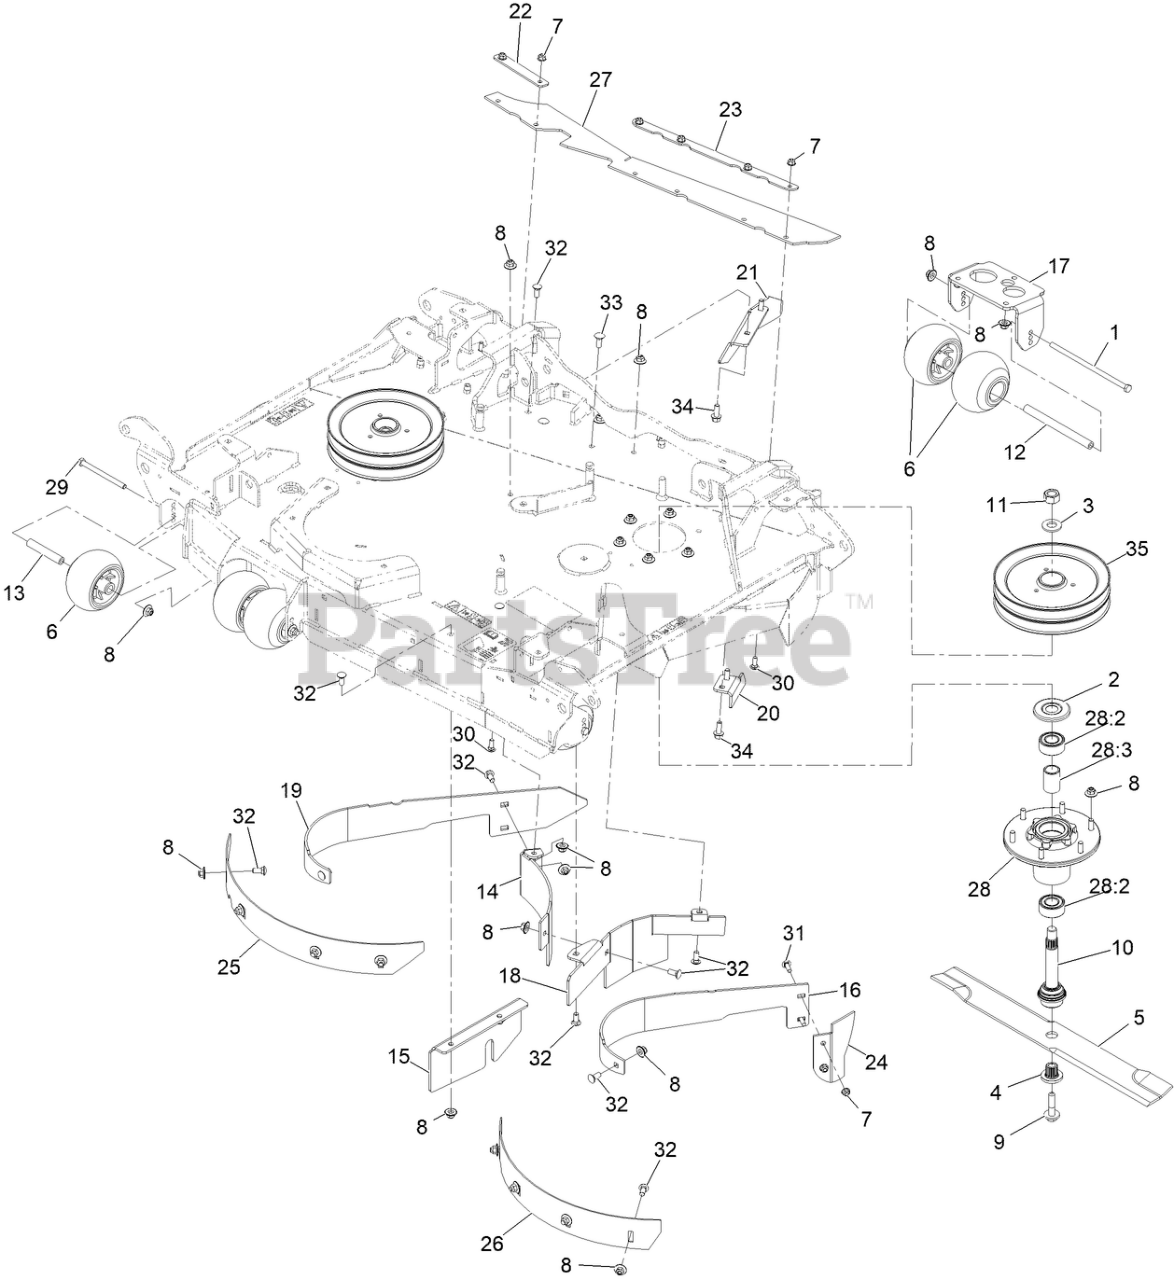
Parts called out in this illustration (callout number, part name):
1	SCREW-HH
2	GUARD-BEARING, TOP
4	BUSHING,SPLINED
6	ROLLER-SCALP, ANTI
7	NUT-HF, NI
8	Nut-Nyloc 3/8-16 Flg
9	SCREW,SEMS 1/2-20 X 2.19
10	ASM-SPINDLE AND SEAL
11	NUT-HEX
12	SPACER-WHEEL
13	SPACER-WHEEL SHORT
14	BAFFLE-CENTER, REAR (RH)
15	PLATE-BLOCK, FRONT
16	BAFFLE-DOGLEG, CENTER (LH
17	BRACKET-ANTISCALP, REAR
18	BAFFLE-CENTER
19	BAFFLE-DOGLEG, CENTER (RH
20	BAFFLE-BREAKER
21	PLATE-FIN, DISCHARGE
22	SUPPORT-FLAP, LH
23	SUPPORT-FLAP, LH
24	GUARD-DISCHARGE
25	BAFFLE-DEPTH, LH
26	BAFFLE-DEPTH, RH
27	FLAP-DISCHARGE
28	ASM-CUTTER HSG
28:2	BEARING-3205 TRASHGUARD
28:3	SPACER-BEARING
29	SCREW-HH
30	SCREW-CARR
31	SCREW-CARR
32	BOLT-CARR
33	BOLT-CARR
34	SCREW-HHF
35	SHEAVE-DOUBLE 96RD
